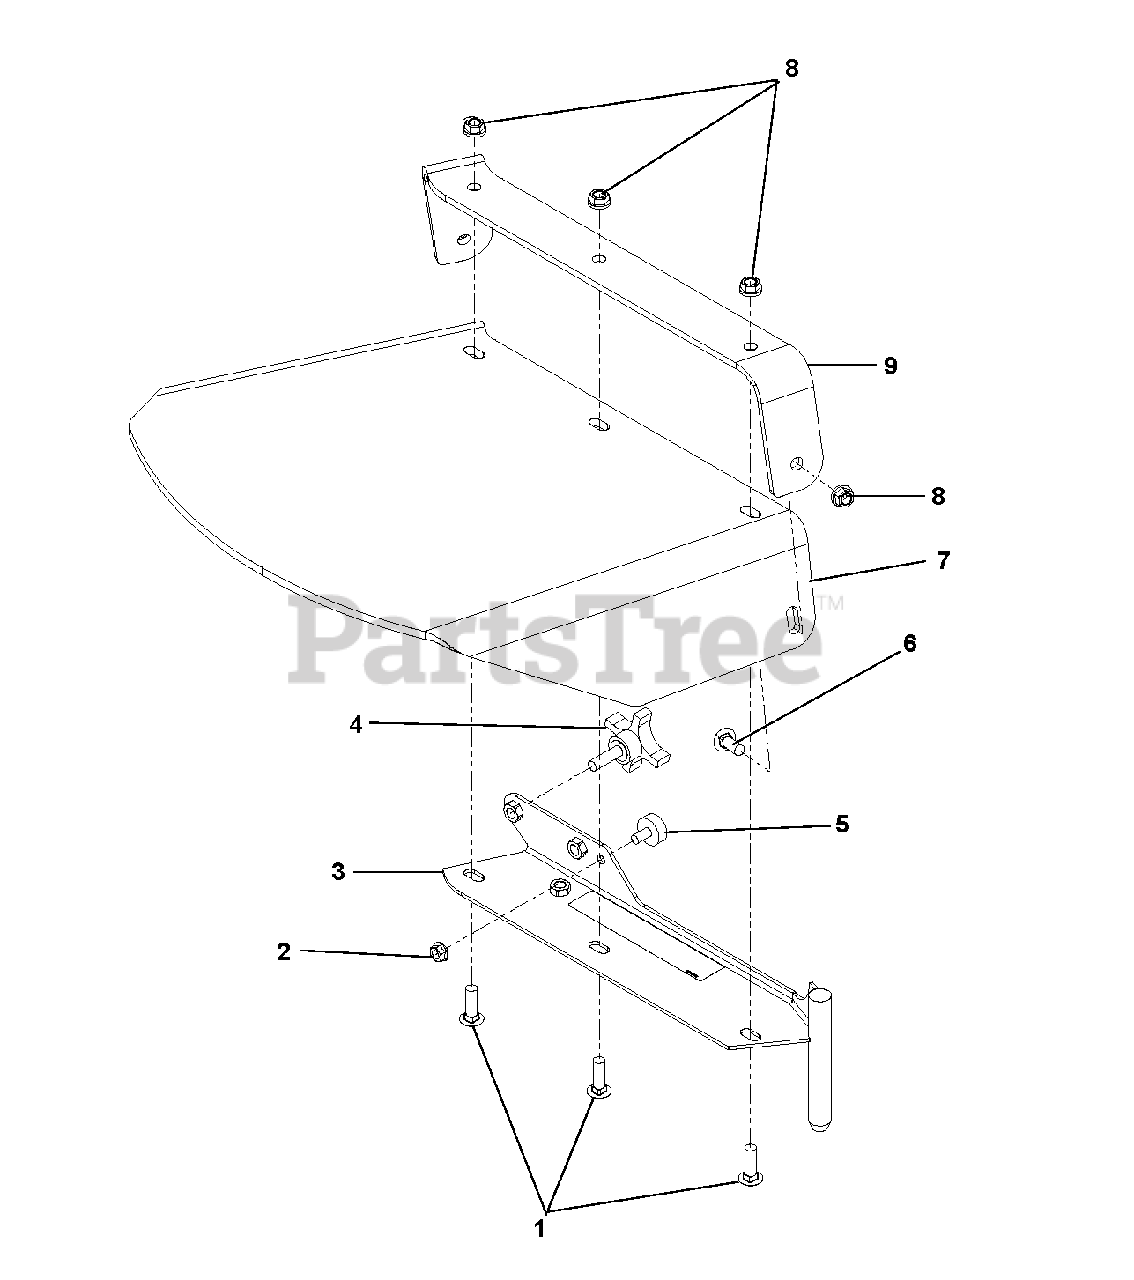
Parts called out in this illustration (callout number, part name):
1	Bolt, Round Head Square Neck .38-16 x 1.25 Grade 5
2	Nut, Spin Lock-Flange .312-18
3	Weldment, Discharge
4	Knob, .375 x 1.25-4 Prong (SN 000101 – 019999)
5	Bumper, Rubber
6	Bolt, Round Head Square Neck .38-16 x 1.00 Grade 5
7	Shield, Walk Rubber Discharge
8	Nut, Spin Lock Flange .375-16
9	Strap, Gravely Walk Rubber Discharge Chute
